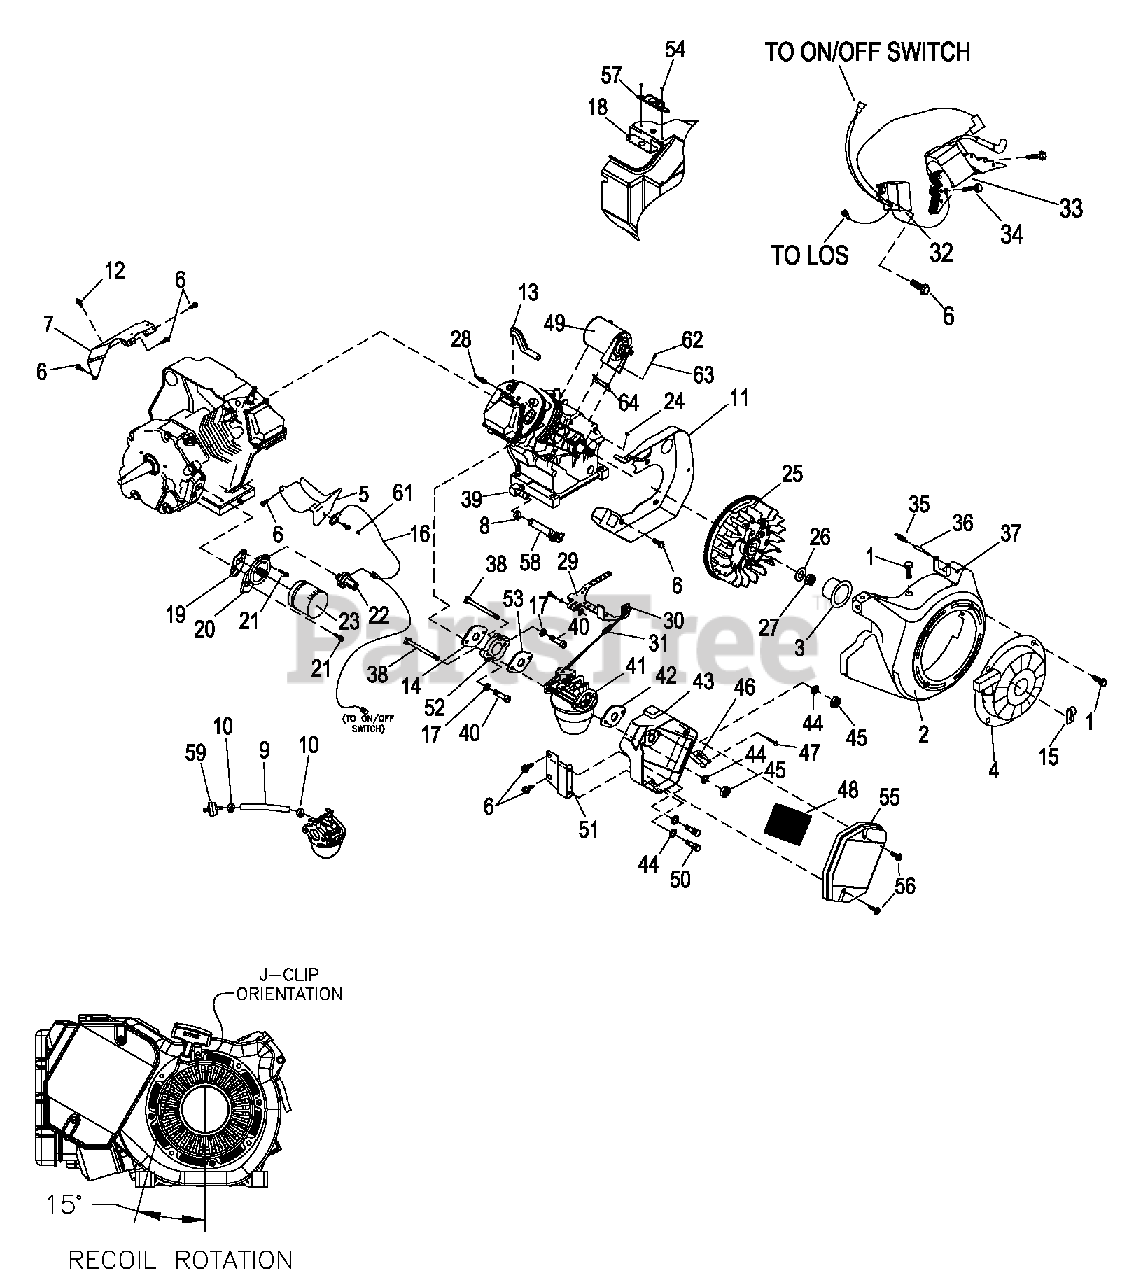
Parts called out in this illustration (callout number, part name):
1	SCREW HHTT M6-1.0 X 8 ZYC
2	ASSEMBLY, BLOWER HOUSING
3	PULLEY STARTER LARGE FRAME
4	RECOIL STARTER LARGE FRAME
5	WRAPPER, BOTTOM 12 HP HS
6	SCREW HHTT M6-1.0 X 10 YELLOW CHROME
7	WRAPPER, TOP REGULAR STEEL
8	CLAMP,HOSE OETIKER STPLSS 18.5
9	FUEL HOSE, 250 MM LONG
10	CLAMP HOSE BAND .41
11	BACKPLATE
12	SCREW, HHTT 5/16-18X1/2" CLEAR
13	HOSE, BREATHER GH410 ENGINES
14	GASKET, INTAKE ADAPTER
15	CLIP-J, VINYL COAT
16	WIRE HARNESS, 410 ENGINE SWITCH WIRING
17	WASHER, LOCK M6-1/4
18	BACK PLATE
19	GASKET,OIL FILTER ADAPTER
20	ADAPTER, OIL FILTER
21	SCREW, SHC M8-1.25 X 30 G12.9
22	SWITCH, HOBBS OIL PRESSURE 5PSI
23	FILTER, OIL BLACK 75 LONG
24	KEY, WOODRFF 4 X 19D
25	FLYWHEEL, RING GEAR 27 DEG
26	WASHER,BELV-20 X 2.2
27	NUT HEX M20-1.5 G8 YLW CHROME- FLYWHEEL
28	SPARKPLUG, CHAMPION RC14YC 0.030"
29	ASSEMBLY,GOVERNOR LEVER 12HP
30	ROD, GOVERNOR CONTROL
31	SPRING, ANTI-LASH
32	OIL PRESSURE SHUTDOWN MODULE
33	ASSEMBLY, IGNITION ADV NO DIODE GH410
34	SCREW, HHTT M6-1.0 X 25 ZINC
35	SPRING GOVERNOR 320/360/410
36	BOLT, GOVERNOR ADJUSTMENT M5
37	NUT, HEX LOCK M5-0.8 NYLON INSERT ZINC
38	BOLT, CARBURETOR MOUNTING
39	BARBED ELBOW 90 DEG 3/8" NPT X 3/8"
40	SCREW, SHC M6-1.0 X 20 G12.9 ZINC PLATED
41	CARBURETOR ASSEMBLY, 410HS
42	GASKET, AIR CLEANER
43	BASE, AIR CLEANER 410 HI FLOW XP PORT
44	WASHER, FLAT M6
45	NUT, HEX LOCK M6-1.0 NYLON INSERT
46	PLATE, SPITBACK
47	SCREW, PLASTITE #8 X .37 LONG
48	ELEMENT, AIR FILTER
49	STARTER, ASSEMBLY
50	SCREW, HHC M6-1.0 X 16 W/ LOCK WASHER
51	BRACKET, AIR CLEANER
52	ADAPTER, "K"
53	GASKET, CARBURETOR/MANIFOLD
54	RIVET, 1/8"
55	COVER, AIR CLEANER 13GN
56	BOLT, AIR CLEANER COVER
57	BRACKET, CHOKE CABLE
58	ASSY OIL DRAIN HOSE, 6" LONG
59	FUEL FILTER
61	GROMMET
62	SCREW SHC M8-1.25
63	WASHER, LOCK M8-5/16
64	SPACER, ENDFRAME
